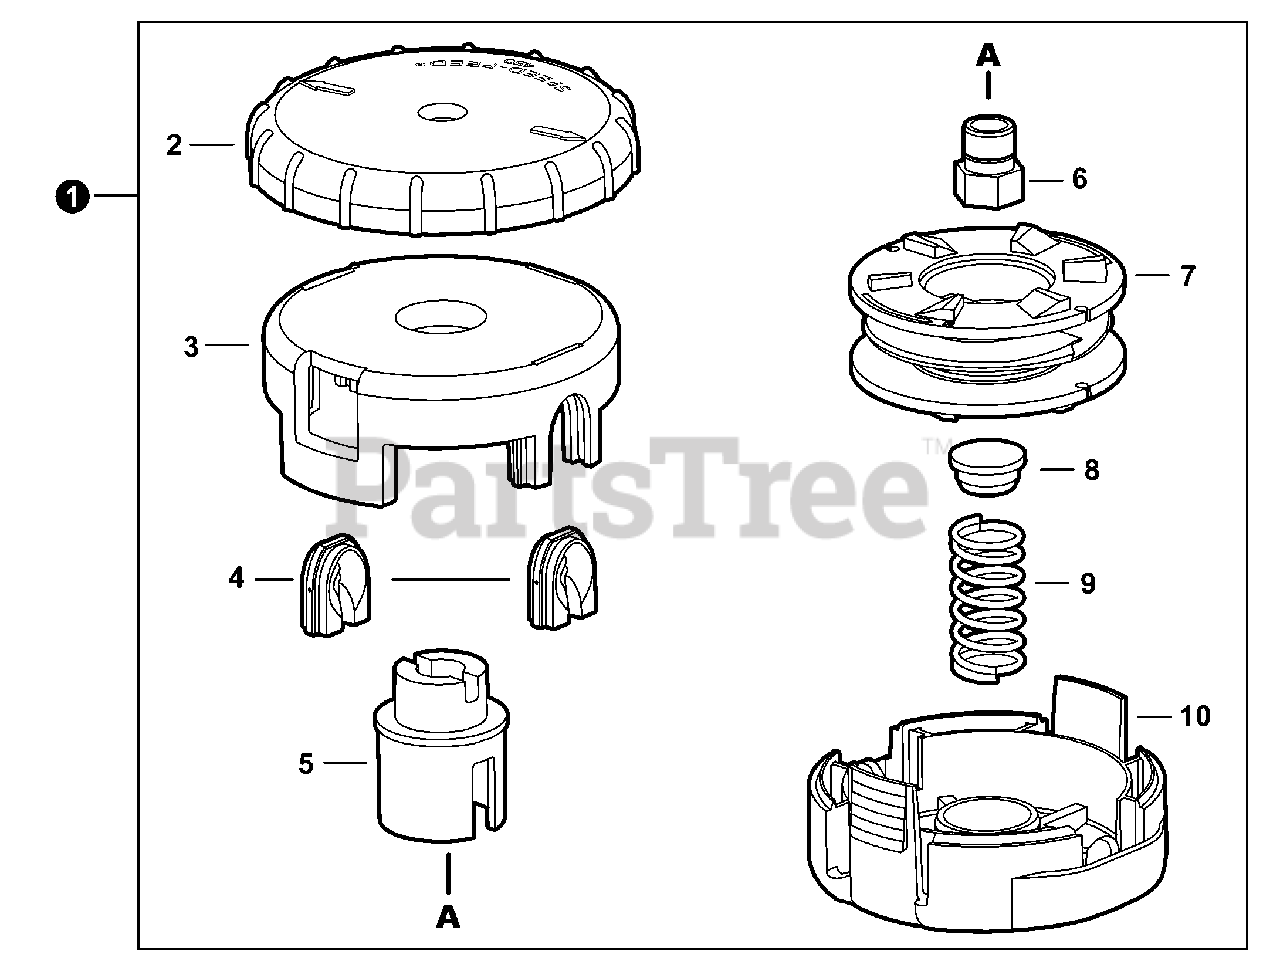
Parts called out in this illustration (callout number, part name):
1	TRIMMER HEAD, SPEED-FEED 450
3	HOUSING, SPOOL
5	HUB, SPOOL
6	BUSHING LH M10×1.25 FEMALE
7	SPOOL LH
8	CAP, SPRING
9	SPRING, COMPRESSION
10	COVER, SPOOL
